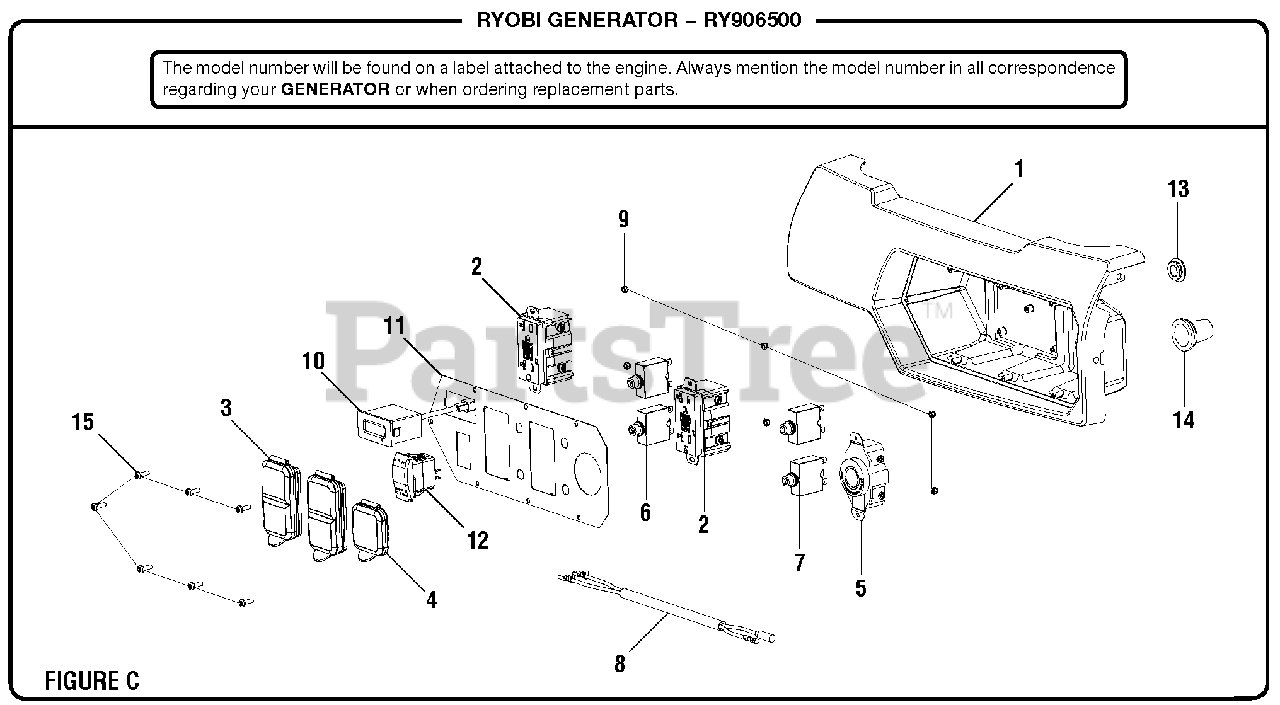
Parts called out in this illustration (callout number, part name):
1	Control Box
2	120 Volt GFCI Receptacle
3	GFCI Receptacle Cover
4	Receptacle Cover (30 Amp)
5	120 Volt Twist Lock Receptacle (30 Amp)
6	Circuit Breaker (20 Amp)
7	Circuit Breaker (30 Amp)
8	Wiring Harness
9	Lock Nut (#6-32)
10	Digital Display
11	Faceplate
12	Stop Switch
14	Rubber Boot
15	Screw (8-18 x 1/2 in.)
